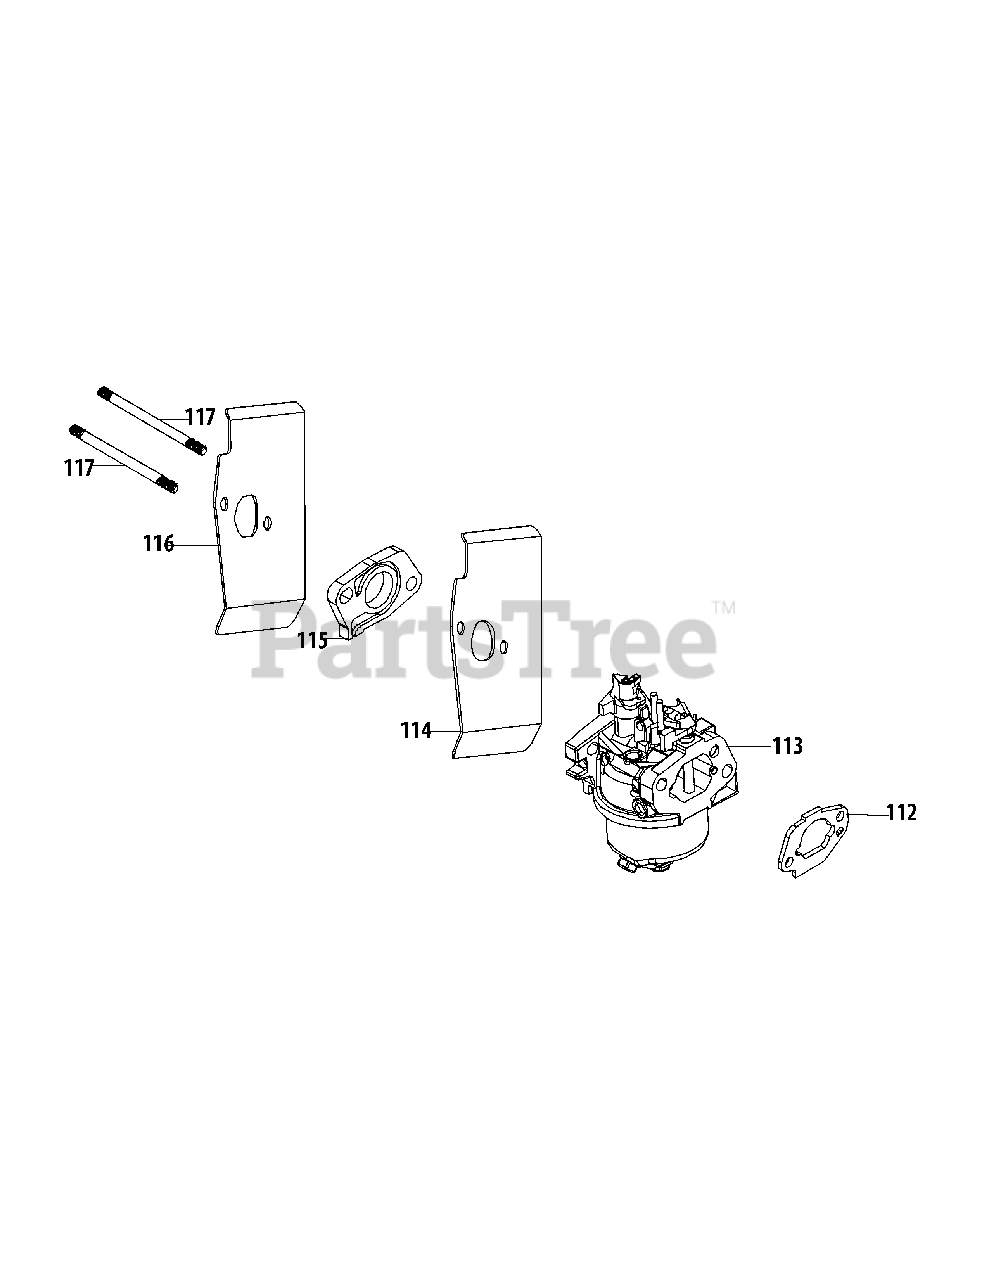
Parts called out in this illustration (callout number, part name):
112	AIR FILTER BASE GASKET
113	CARBURETOR ASSEMBLY
113	CARBURETOR REBUILD KIT
114	CARBURETOR GASKET
115	CARBURETOR INSULATOR
116	CARBURETOR GASKET
117	CARBURETOR STUD-M6 x 87
